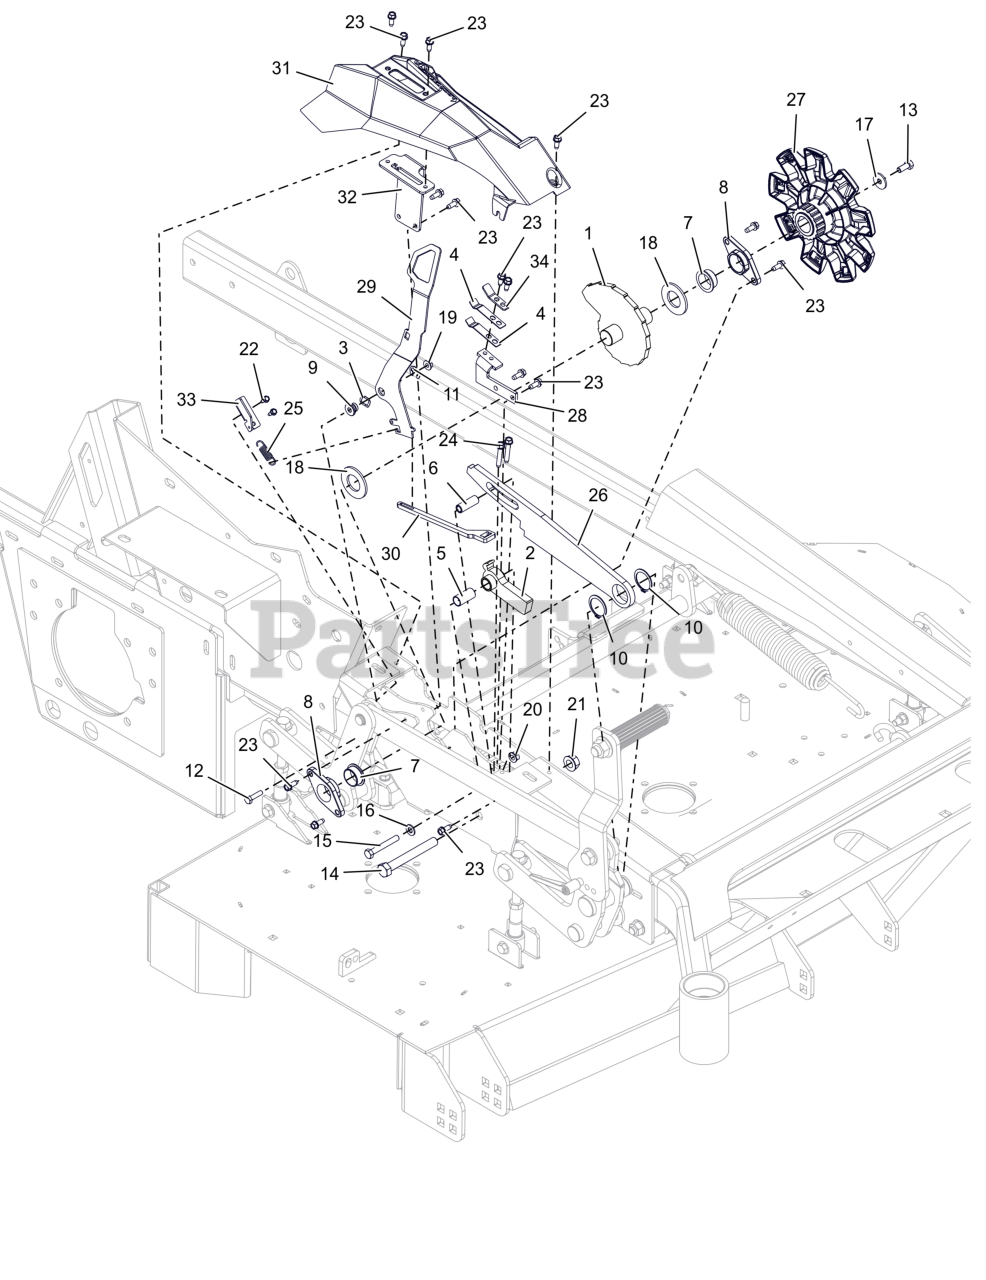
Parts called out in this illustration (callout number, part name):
1	WLDMT, HOC
2	WLDMT, TRANSPORT LOCK PAWL (BLACK)
3	WAVE WASHER .531X.781X.125FH
4	ARM, HOC DETENT
5	SPCR-SLV .531 X .625 X 1.25
6	SPCR, SLV .328 X .439 X 1.381
7	BSHG-FLG 1.0X1.125X.50X1.375 R
8	BSHG, 1.000X1.375X.650
9	BSHG FLANGED .270 X .500 X .468 X .75
10	RG-RET-EXT 1.25 X .050
11	RG-RTNG-EXT .500X.042 (E)
12	BLT,HEX .25-20X1.00 G5 ZCC
13	BLT,HEX .31-18X.75 G5 ZCC
14	BLT, HEX .50-13X4.00 G5 ZCC
15	BLT, HEX .31-18X2.25 G5 ZCC
16	WSHR,FLT .344X.688X.065 ZCC
17	WSHR,FLT .328X1.00X.094 ZCC
18	WSHR-FL-STL 1.062X2X0.134 ZCC
19	NUT-LK-CTR-FLG .25-20 ZC120
20	NUT,LK-CTR-FLG .31-18 GF ZCC
21	NUT-LK-CTR-FLG .500-13 GG ZCC
22	SCR,TAP #10-24X.50 HWH TR ZCC
23	SCR,TAP .25-20X.625 HWH ZCC
24	SCR-TAP .25-20X1.50 HWH ZCC
25	SG-TENS .063X.44X1.56
26	ARM, HOC LINK (BLACK)
27	WHEEL, HOC INDEX
28	BRKT, HOC DETENT MTG (BLACK)
29	LEVER, TRANSPORT LOCK (BLACK)
30	ARM, TRANSPORT LOCK (BLACK)
31	COVER, TRANSPORT LOCK
32	PLATE, TRANSPORT LOCK POSITION (BLACK)
33	BRKT, SPRG (BLACK)
34	TAB, REINFORCING (BLACK)
